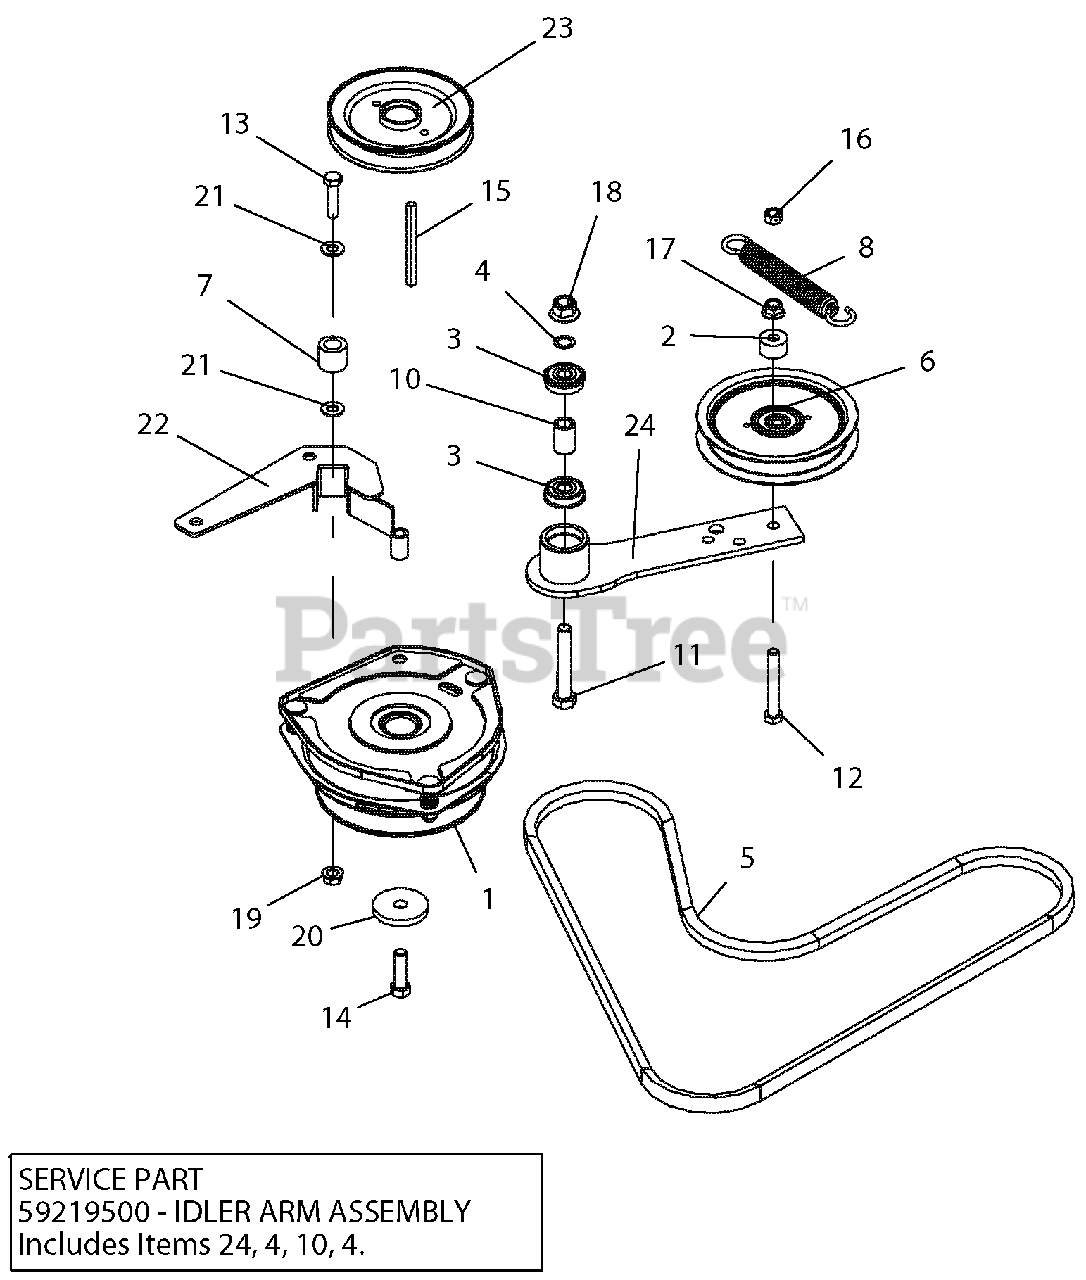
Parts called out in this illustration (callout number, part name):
1	CLUTCH-OGURA
2	SPACER .390X1.000X.562
3	BRG, BALL .501 X 1.38 X .438 SEALED
4	WASHER-FLAT-STL, .500 X .750 X .020
5	BELT, B RAW COGGED
6	IDLER, FLAT - 5.00" X .75"
7	BUMPER, RUBBER .62 X 1.0 X .88 LG
8	SPRG, EXTENSION
10	SPACER, .510 X .750 X 1.148
11	BLT-HEX .50-13X3.00 GR5 YWZC
12	BLT-HEX .38-16X2.75 GR5 YWZC
13	BLT-HEX .38-16X1.50 GR5 YWZC
14	BLT-HEX .44-20X1.50 GR8 YWZC
15	KEY-SQ .250X.250X3.50
16	NUT-LK-CTR .38-16 YWZC
17	NUT-LK-NYL-FLG .38-16 YWZC
18	NUT-LK-NYL-FLG .50-13 YWZC
19	NUT, LK-TOP-FLG .38-16 YWZC
20	WSHR-FL-STL .469X2.00X.25 YWZC
21	WSHR-FL-STL.406X.812X.065 YWZ
22	WMT, CLUTCH STOP - BLACK
23	SHEAVE, ENGINE 1.127 ID X 5.250 OD-BLACK
24	WLDMT, HYDRO DRIVE IDLER ARM-BLACK
